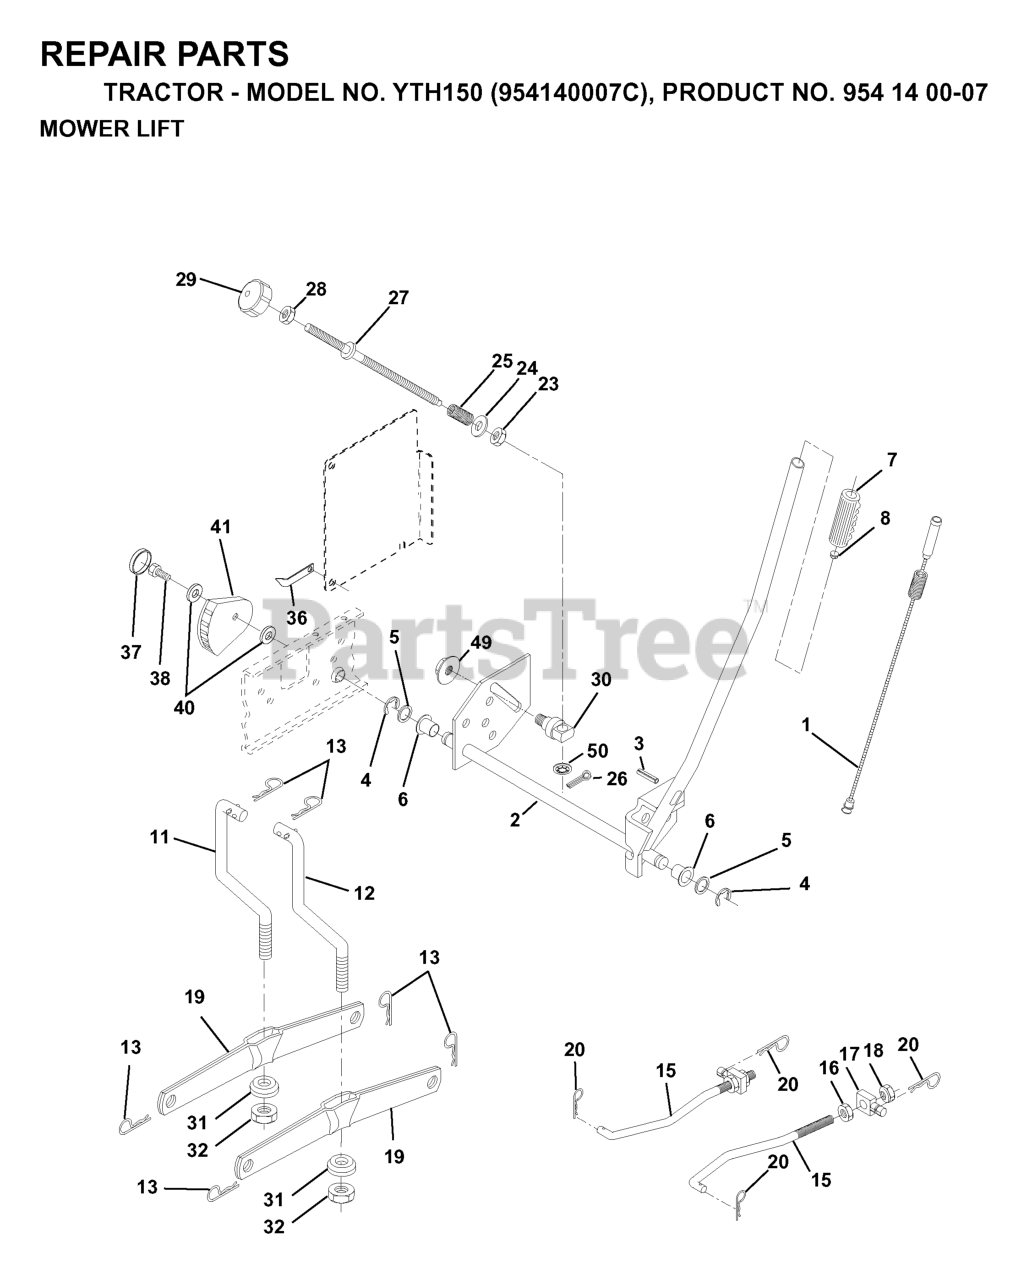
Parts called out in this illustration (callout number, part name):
1	WIRE ASM INNER W/ PLUNGER LT
2	SHAFT ASM R HANDLE
3	PIN GROOVE.
4	RETAINING RING LT
6	BEARING.NYLON
7	GRIP HANDLE
8	PLUNGER BUT KIT
11	LINK LIFT LH
12	LINK LIFT RH
13	RETAINER-SPRNG RB
15	FRONT LINK
16	NUT.HEX.JAM.1/2-13
17	TRUNION
18	NUT.LK.W/WSH.1/2.
19	ARM.REAR.SUSPENSION
20	SPRING RETAINER
25	SPRING**
26	COTTER PIN
27	ROD ADJ LIFT
28	NUT
29	KNOB INF 3/8-16
31	BEARING PIVOT
32	NUT CROWNLOCK 3/8-24
36	POINTER, HEIGHT INDICATOR(2 2)
38	SCREW.THDROL.5/16-18X3/4.TTY
41	IND. HEIGHT STLT
49	NUT
50	NUT PUSH M
